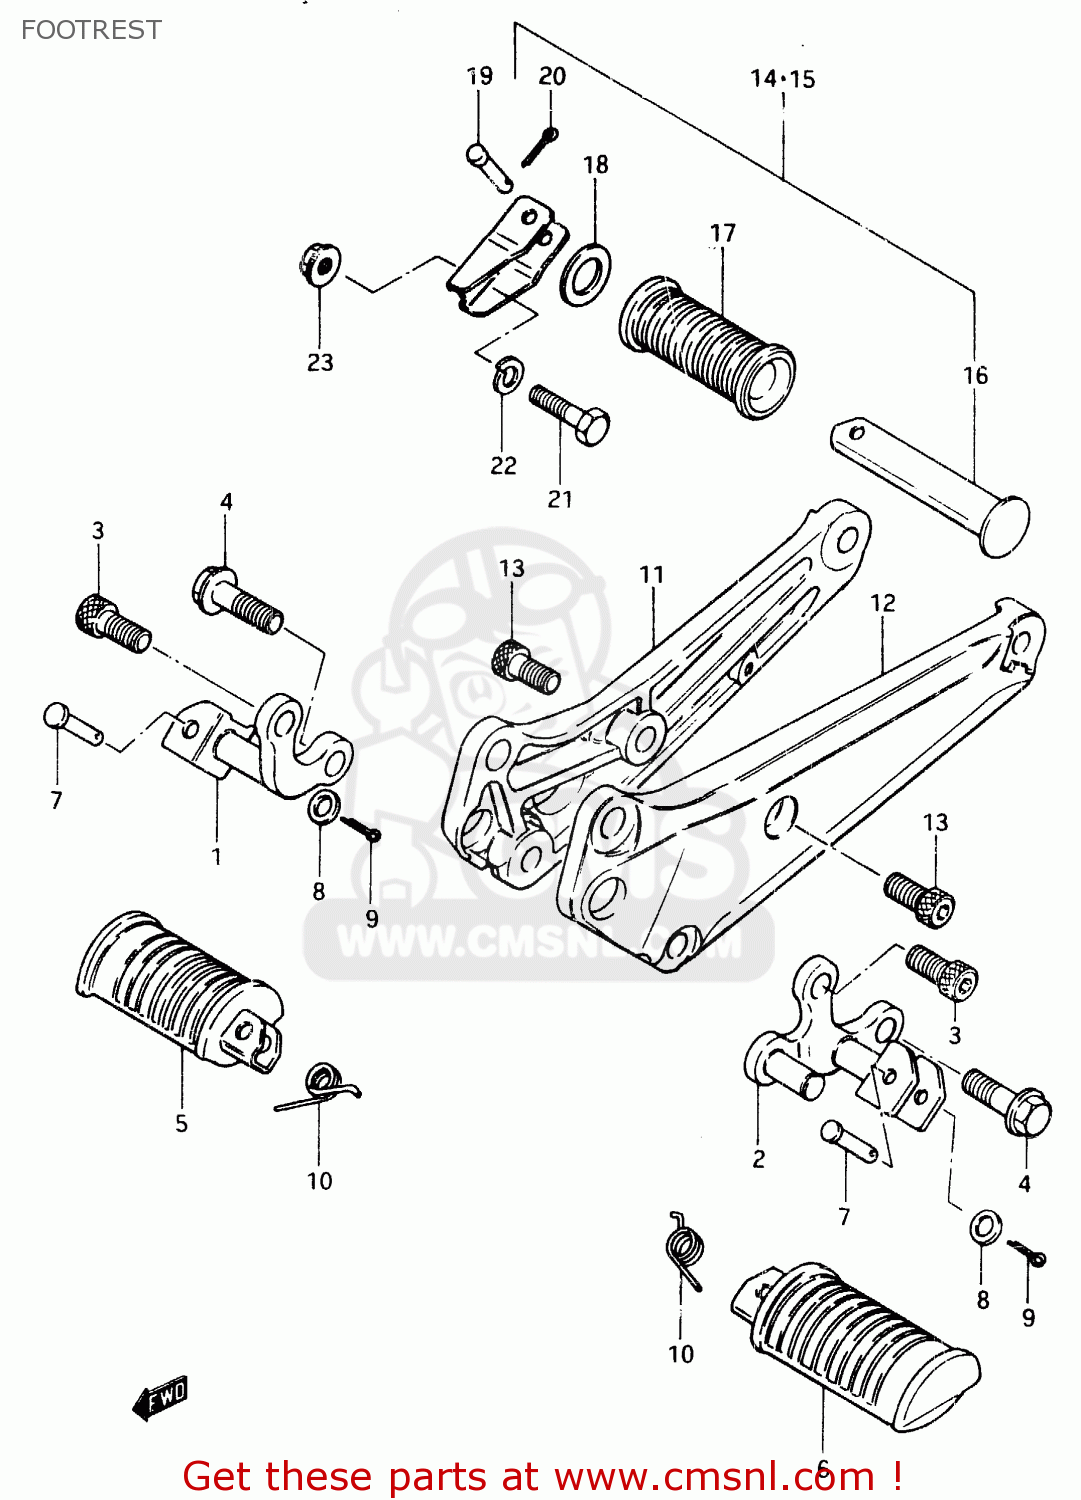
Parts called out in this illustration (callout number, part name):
1	BAR, FRONT FOOTREST RH
2	BAR, FRONT FOOTREST LH
3	BOLT
4	BOLT, LOWER
5	RUBBER,FR FOOT
6	RUBBER, LH
7	PIN
8	WASHER
9	PIN 20X20
10	SPRING
11	BRACKET, MUFFLER RH
12	BRACKET, MUFFLER LH
13	BOLT
14	FOOTREST, PILLION RH
15	FOOTREST, PILLION LH
16	BAR,FOOTREST RUBBER
17	RUBBER,PILLION FOOTREST
18	WASHER (19.5X32X2)
19	PIN
20	PIN 20X20
21	BOLT,M10X1.25X
22	LOCK WASHER
23	NUT
